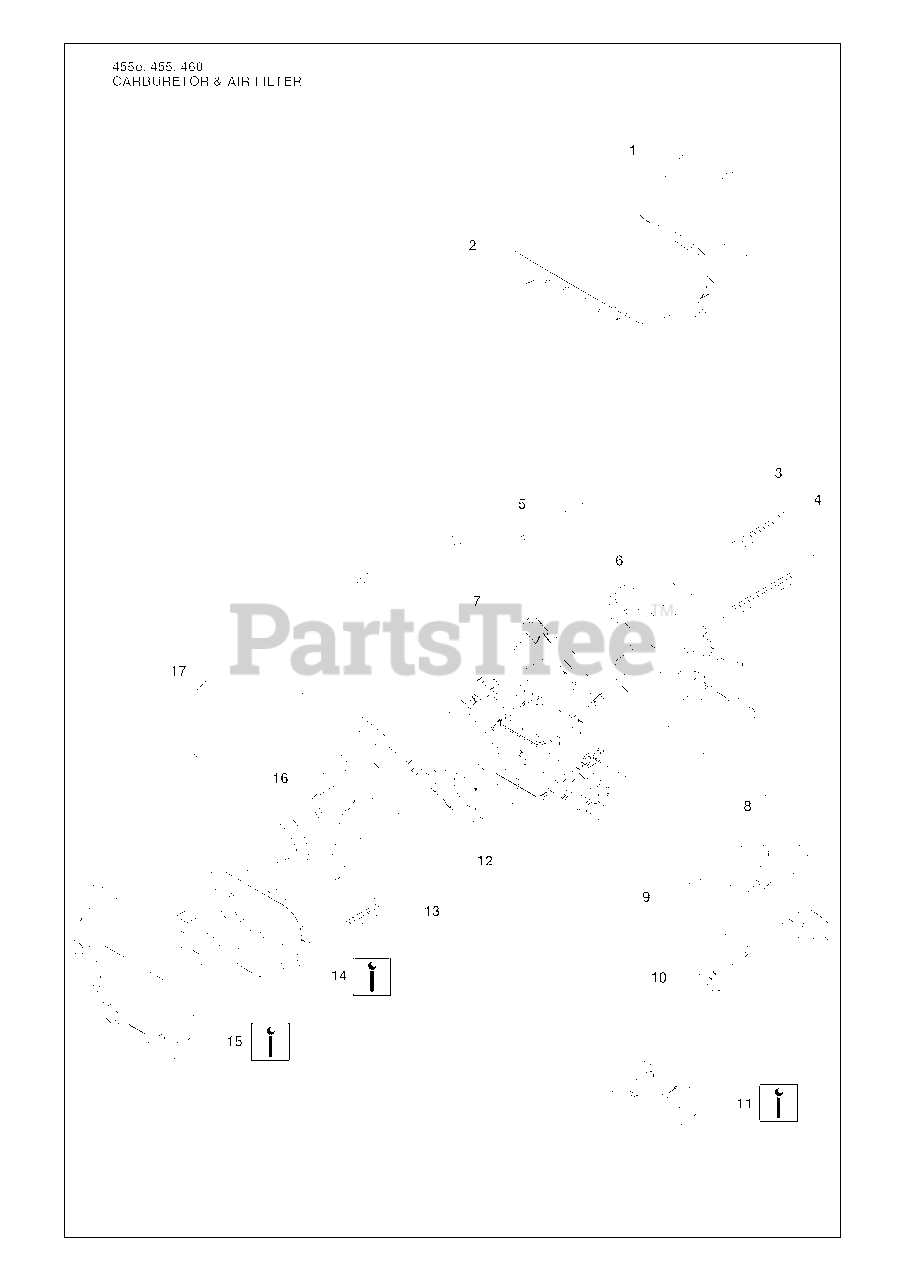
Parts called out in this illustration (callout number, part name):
2	AIR FILTER
5	THROTTLE ROD
6	FILTER HOLDER
7	CARBURETOR
8	STOP LEVER
10	CHOKE CONTROL
11	GUIDE SLEEVE CARB
14	INDUCTION MANIFOLD
17	FUEL HOSE
